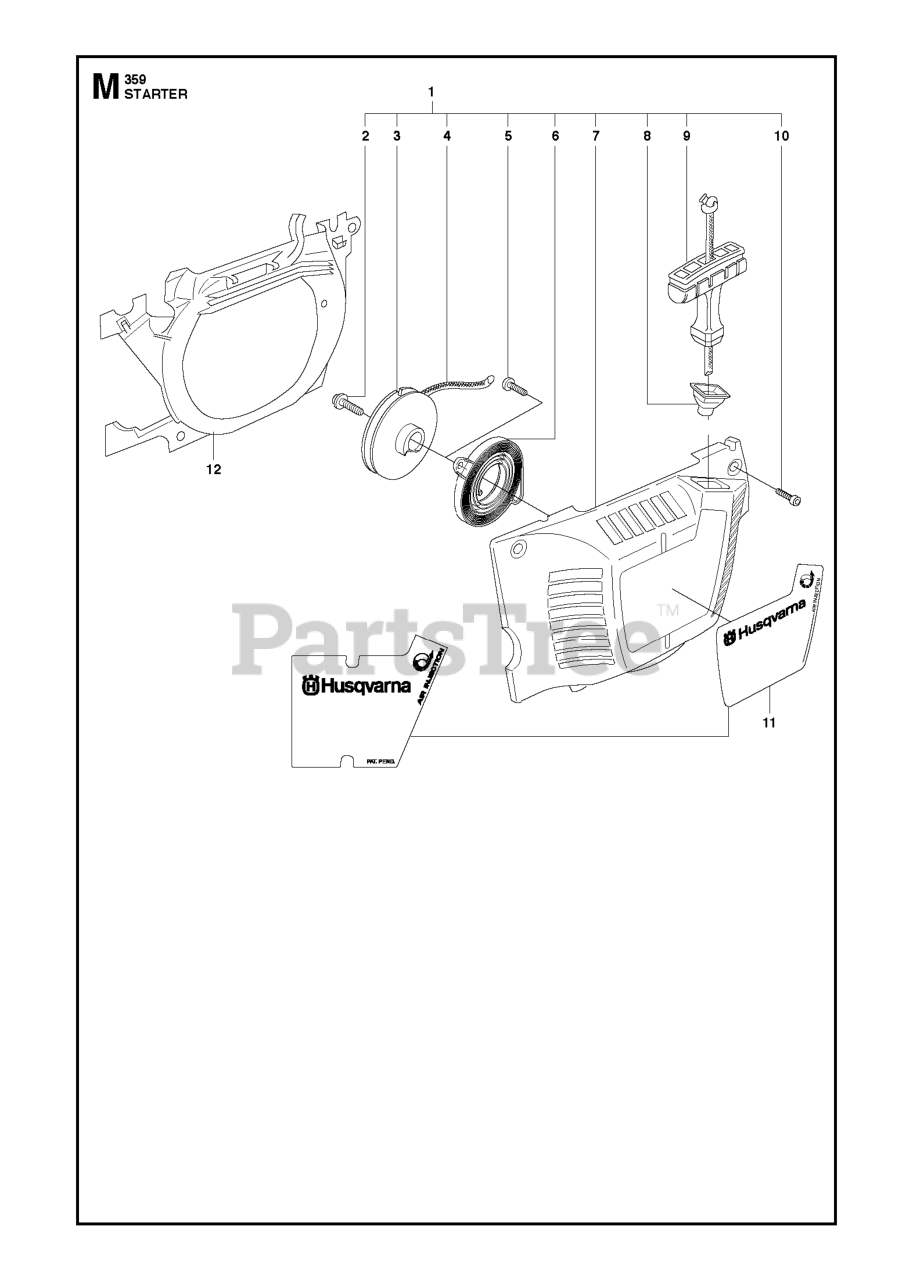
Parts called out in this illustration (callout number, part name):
1	STARTER DEVICE COMPLETE
3	STARTER PULLEY
4	STARTER ROPE
6	RETURN SPRING
7	STARTER HOUSING.
9	STARTER HANDLE
10	SCREW.CIHPANMO M5X19 10.9
11	DECAL
12	AIR CONDUCTOR
